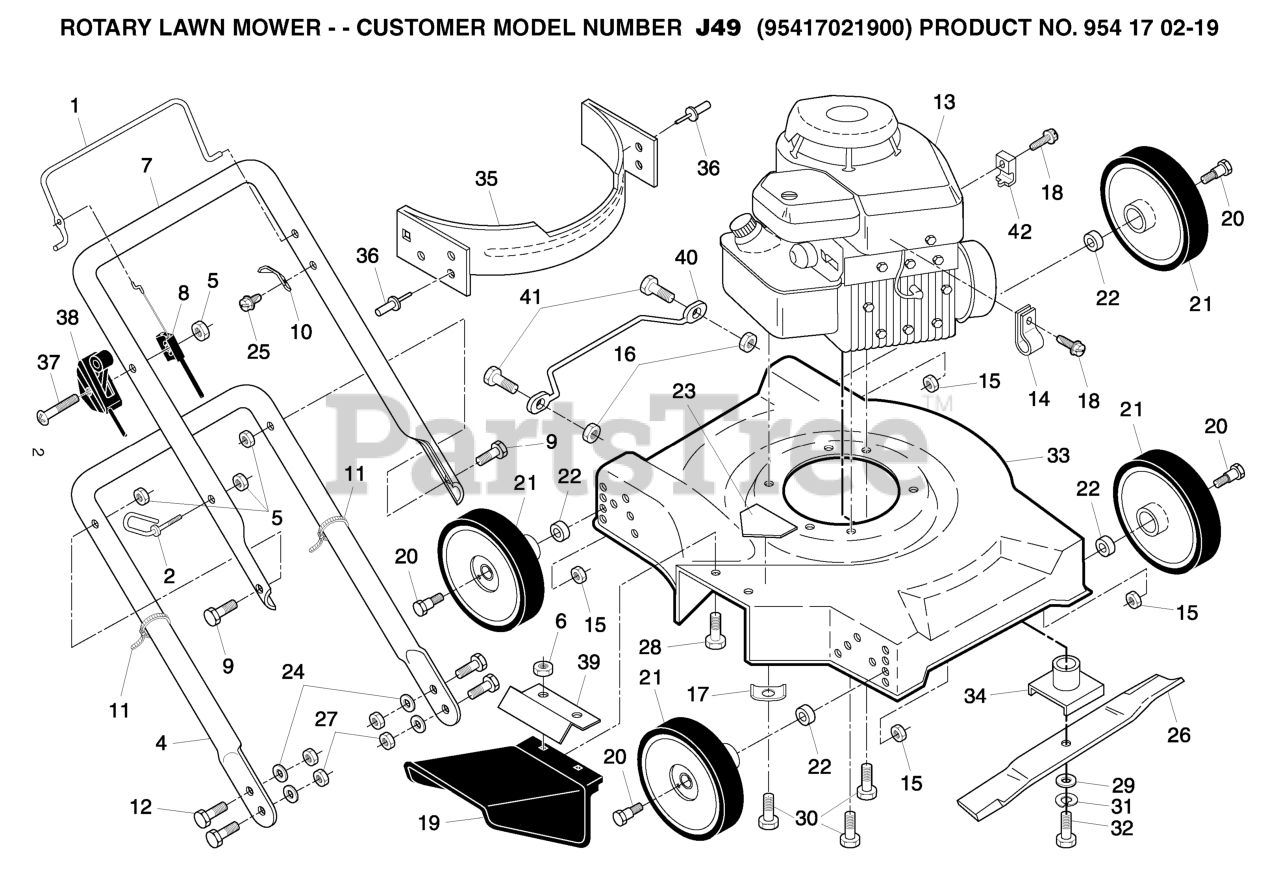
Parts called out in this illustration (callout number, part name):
1	BAIL.MZR.STD.BLACK
2	ROPE, GUIDE
5	NUT
6	LOCKNUT.NYLOC.1/4-20
8	CABLE.CONTROL.MZR.RH.SP/PUSH
9	BOLT
10	BRACKET UPSTOP
11	TIE GUIDE
14	WASHER
15	LOCKNUT PM
17	WASHER.ENGINE.BZP
18	SCREW.HEX.HEAD.WASHER.10-16
21	WHEEL
22	SPACER.WHEEL.390.X1.0X.380.RTA
23	DECAL.INTERNATIONL.CUTFINGER
26	20" Blade
27	FLANGED LOCKNUT 3/8-16 ZINC
28	BOLT.HEX.1/4.X.3/4.DICHROMATE
29	WASHER,HARDEN
30	BOLT 3/8-16X1-1/8
31	LOCKWASHER
32	SCREW, HEX HD 3/8-24 X 1-3/8
34	BLADE ADAPTOR
35	FRONT BAFFLE
36	RIVET BLIND
37	SCREW.PAN.HEAD
41	REPL BY 817 02 10-08
42	GUIDE CLIP PM
